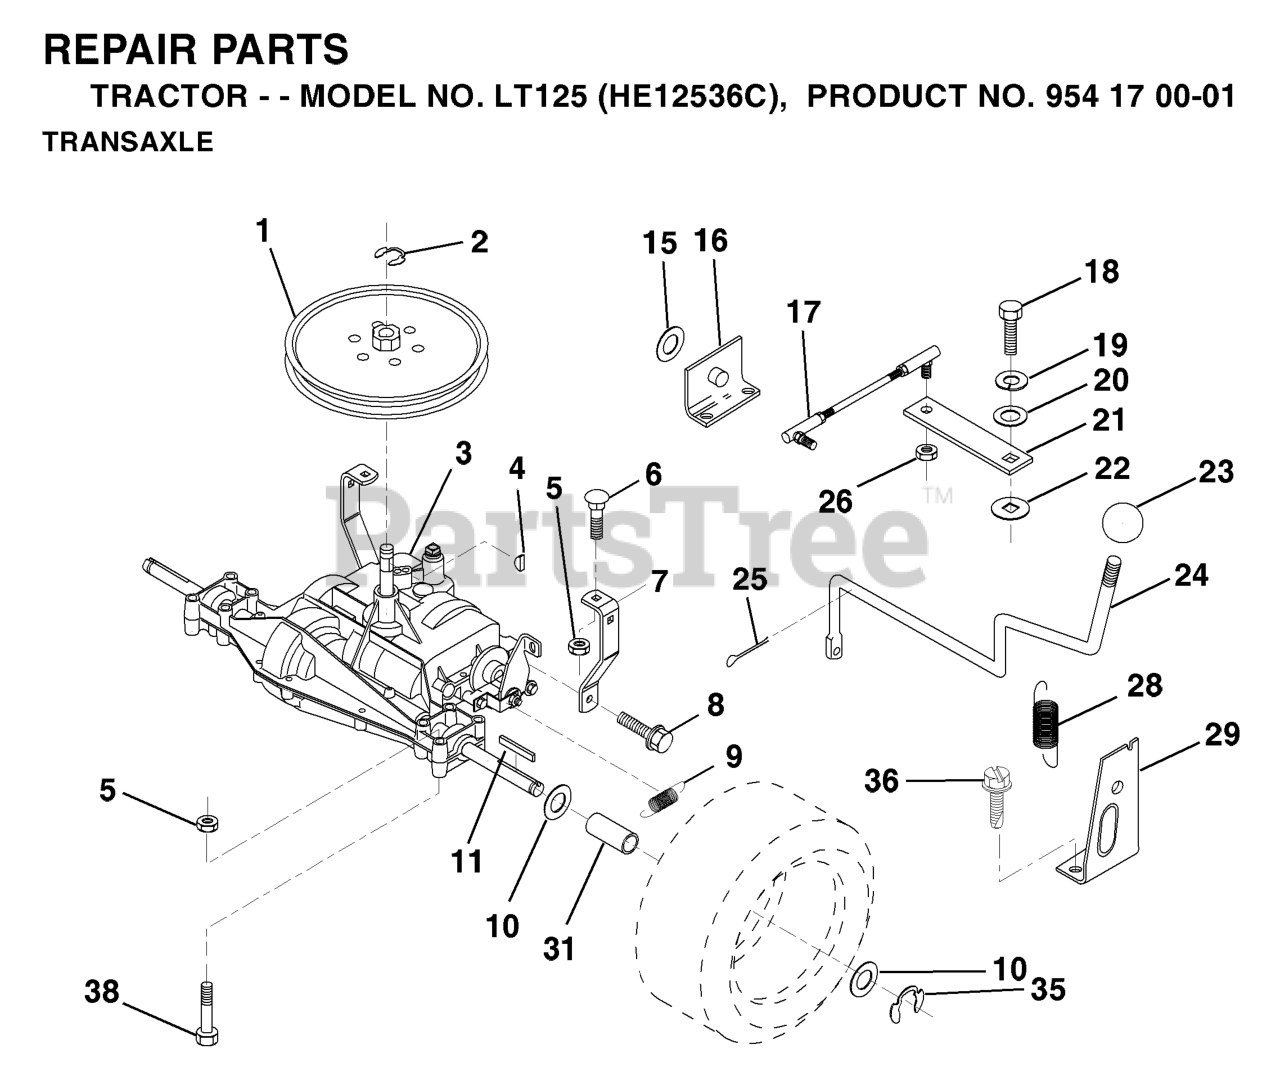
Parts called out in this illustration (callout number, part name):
2	RETAINING RING LT
4	KEY STD (1373) DANA
5	LOCKNUT
6	RP BOLT 5/16-18 X3/4 ZN/YEL GR
7	STRAP,TORQUE
8	SCREW.THDROL.5/16-18X3/4.TTY
9	SPRING,BRAKE RETURN
11	SQUARE KEY
15	WASHER
16	SUPT, HDLE SHT LH
18	BOLT 1/4-28X3/4
19	LOCKWASHER
22	WASH-SHFT PLT LT
23	KNOB T (1/2-HOLE)
24	ROD, SHIFT
25	PIN COTTER
26	LOCKNUT
28	SPRING.EXTENSION
29	SUPPORT HANDLE SHAFT RH
31	SPACER AXLE
36	SCREW
38	BOLT HEX 5/16-18 GR 5
